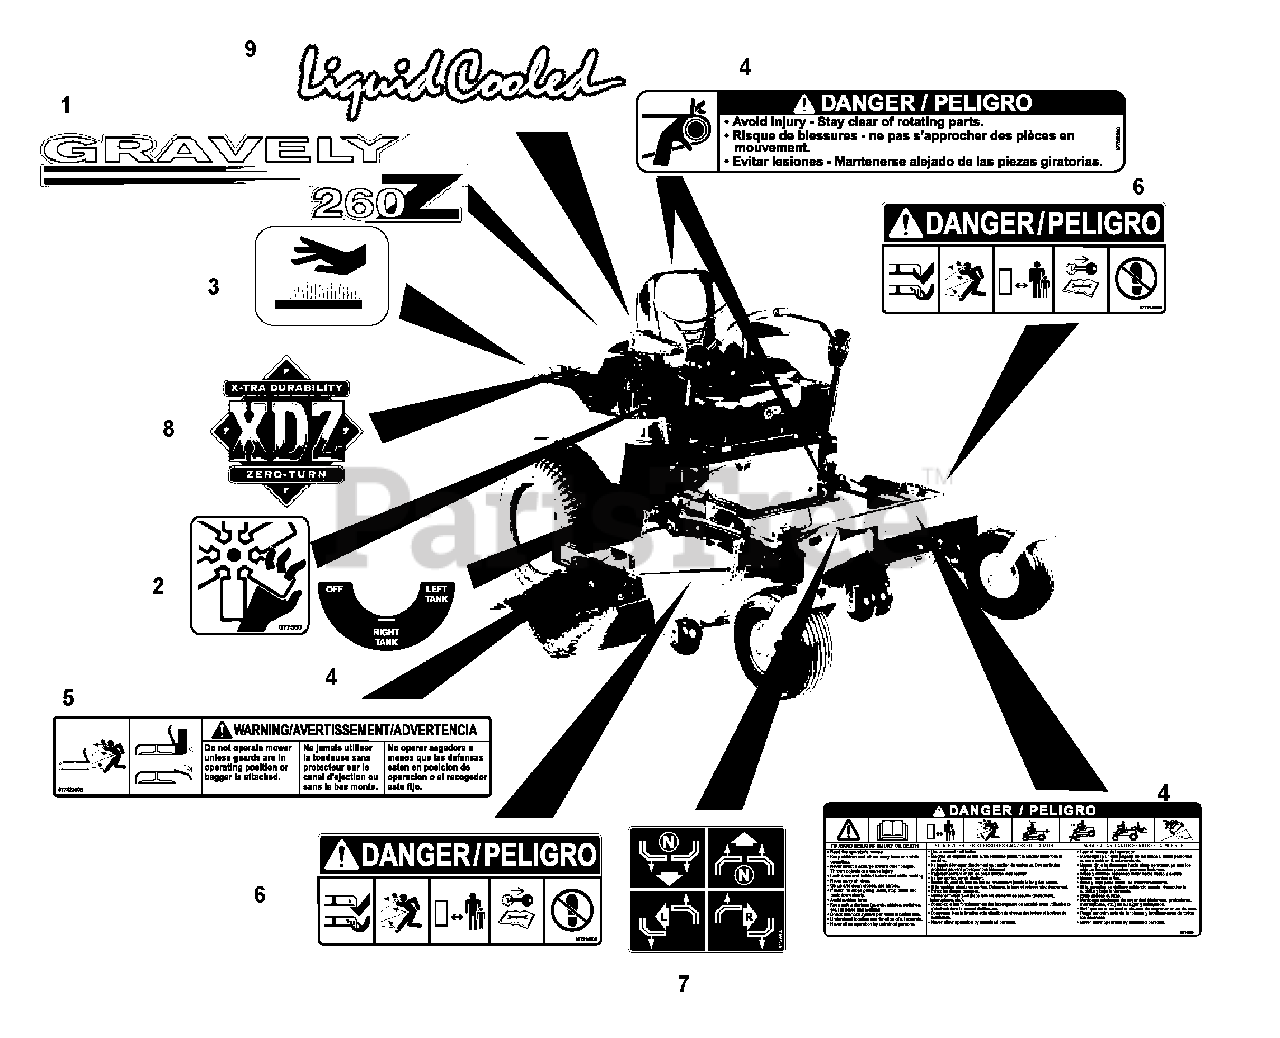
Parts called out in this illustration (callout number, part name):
1	Decal, PM-252Z Hood
1	Decal, PM-260Z Hood
1	Decal, PM-272Z Hood
2	Decal, Danger Fan
3	Decal-Hot Surface
4	Set, Decal-Common Danger/Fuel
5	Decal, Warning
6	Decal, Mower Pan Head Danger
7	Decal-Instructional
8	Decal, XDZ
9	Decal, Liquid Cooled
